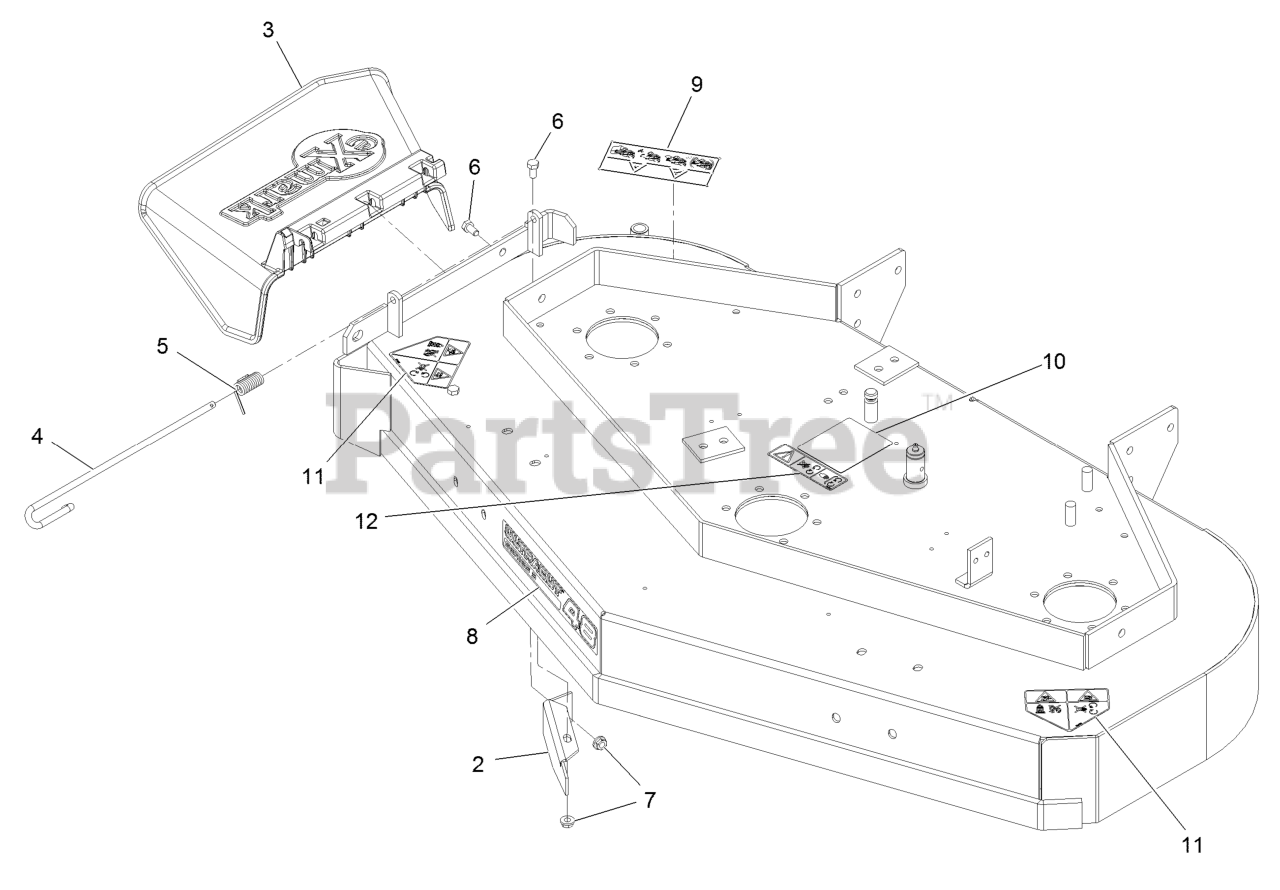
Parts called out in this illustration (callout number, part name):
2	BAFFLE-DOGLEG
3	CHUTE DEFLECTOR XRK M056
4	PIN-CHUTE
5	SPRING, TORSION
6	SCREW-HH
8	DECAL-ULTRACUT 48 SERIES
9	DECAL-WARNING, BAGGER
10	DECAL-ROUTING, BELT
11	DECAL-DANGER
12	DECAL-COVER, MISSING
